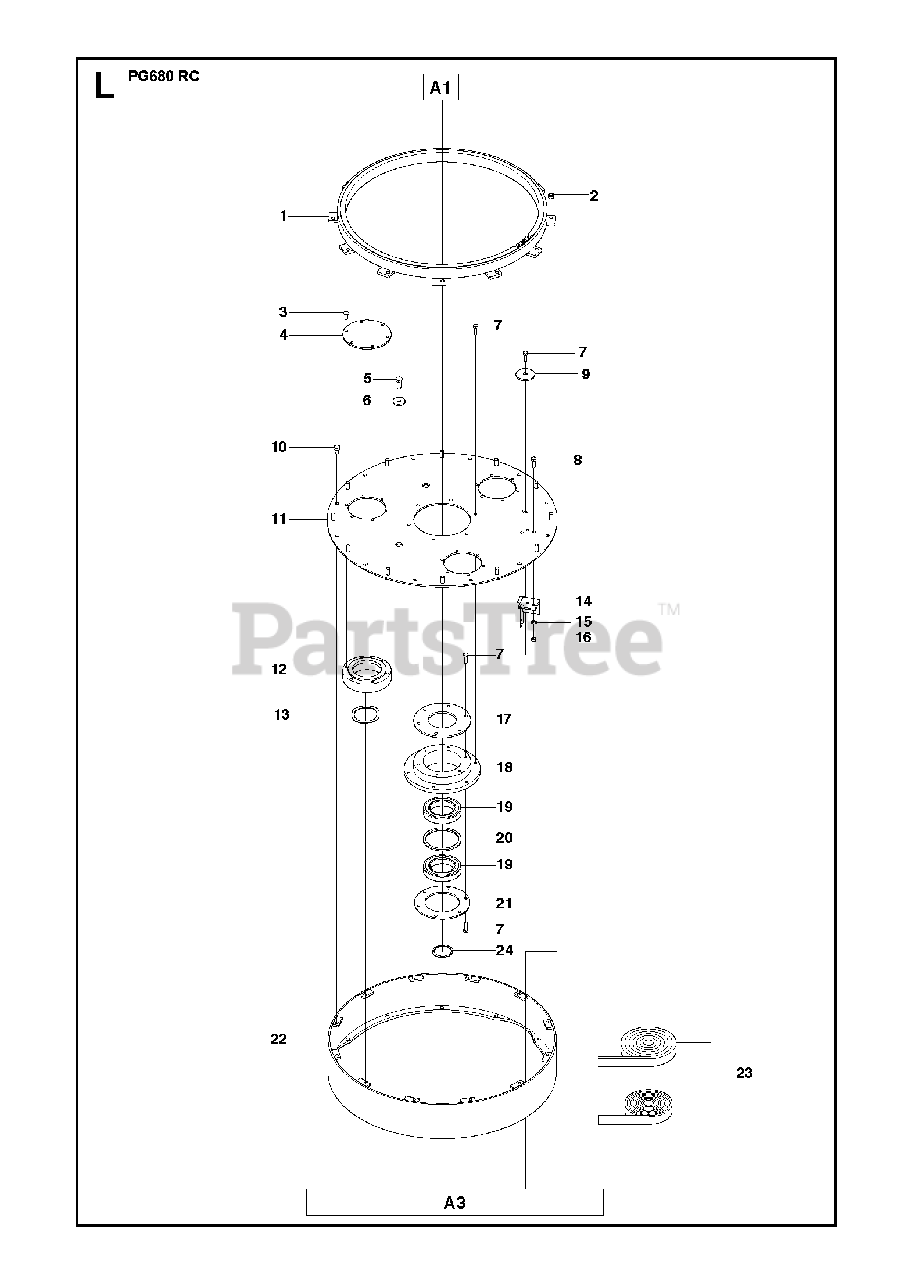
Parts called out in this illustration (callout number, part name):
2	HEXAGON LOCKING NUT
15	WASHER
16	HEXAGON LOCKING NUT
